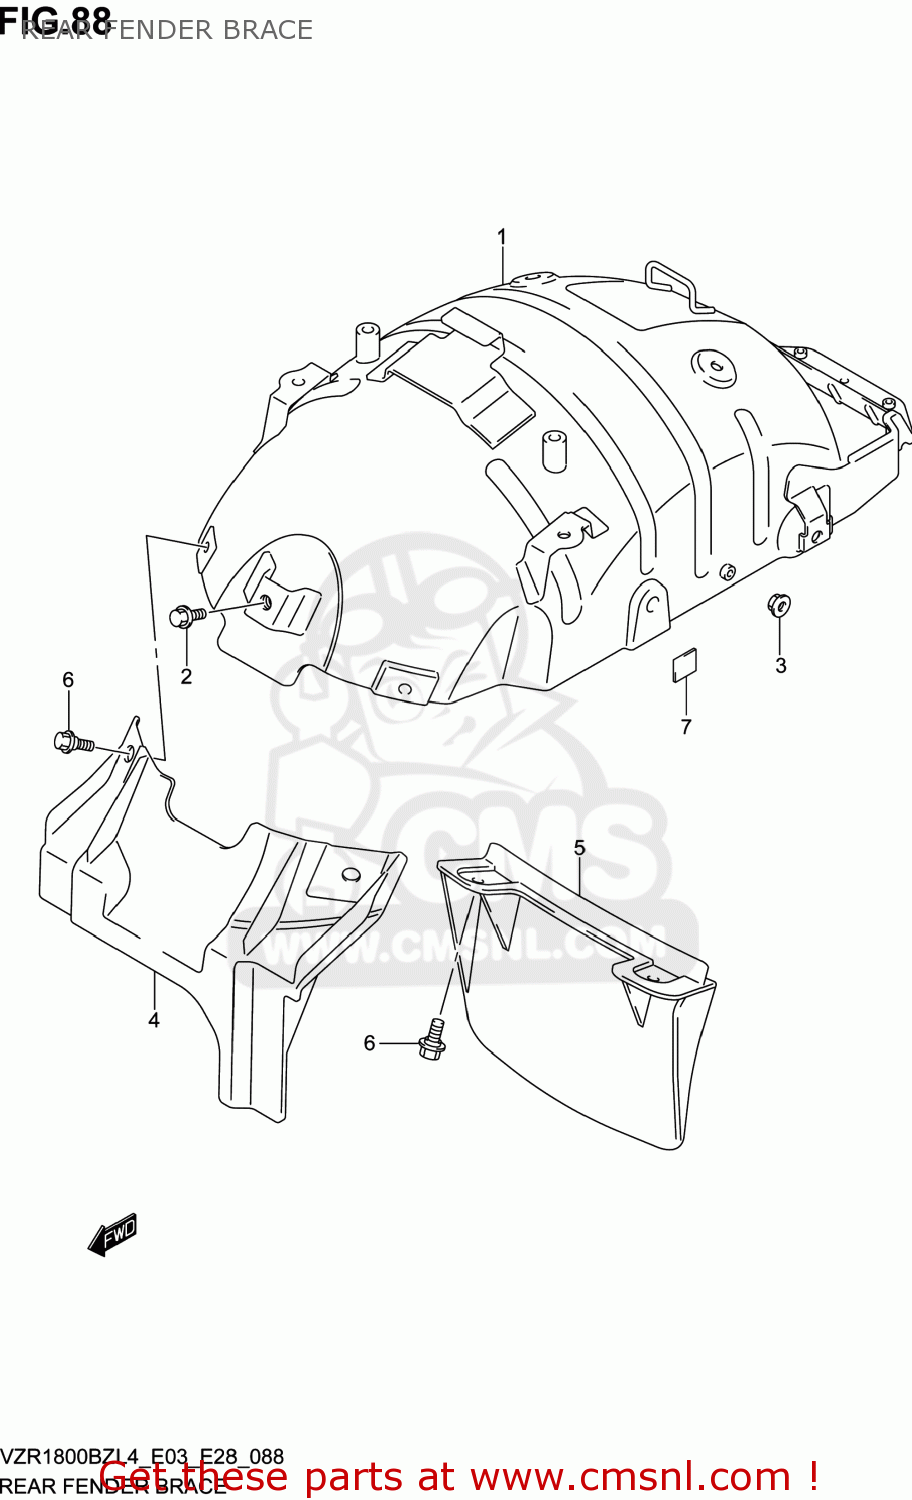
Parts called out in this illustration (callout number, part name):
1	BRACE,RR FENDER
2	BOLT
3	NUT
4	MUDGUARD,RR FENDER FR UPR
5	MUDGUARD,RR FENDER FR LWR
6	BOLT(6X12)
7	CUSHION,CABLE GUIDE
